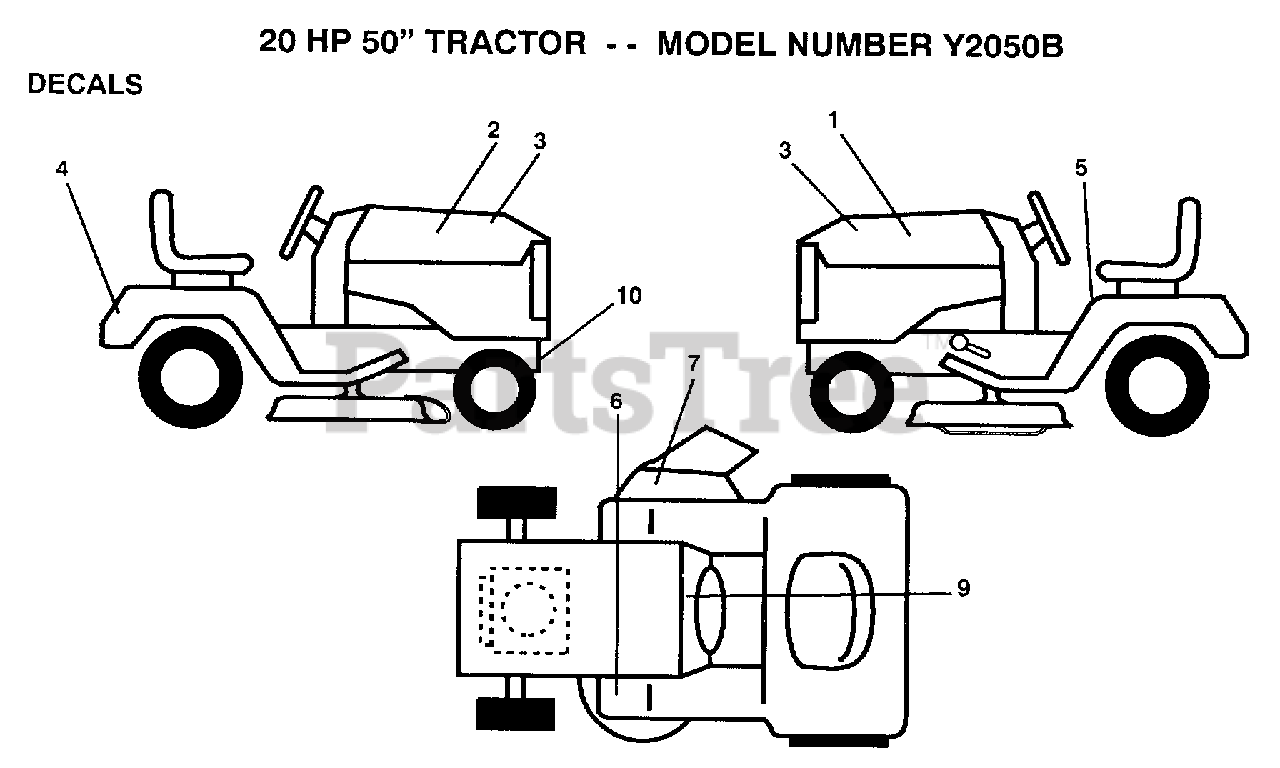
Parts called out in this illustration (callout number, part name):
1	DECAL HOOD LH
5	DECAL CAUTION
6	DECAL T
7	DECAL WARNING
